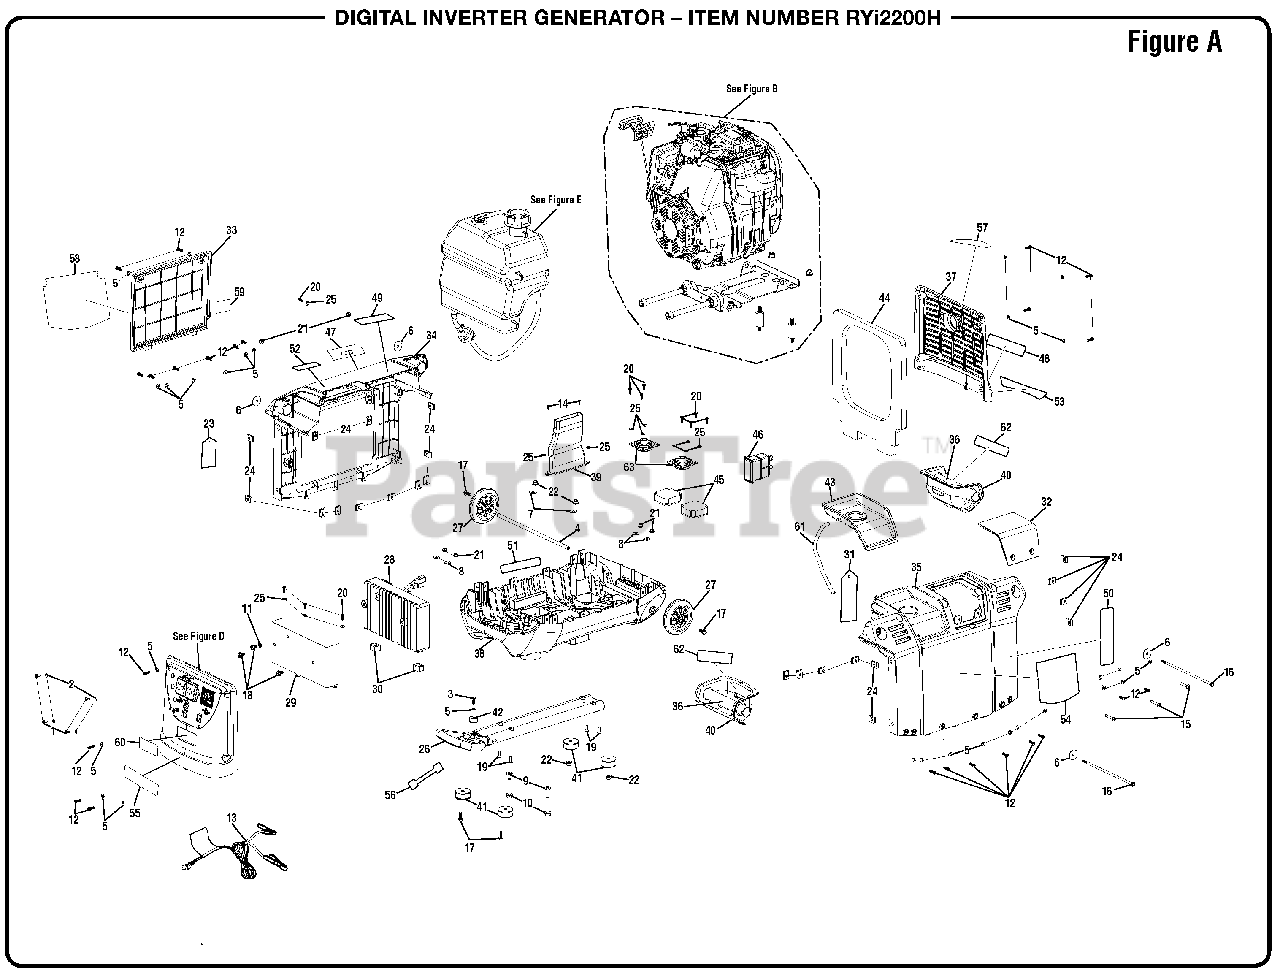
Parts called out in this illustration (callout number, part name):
1	Screw w/Washer (M4 x 10 mm, T20 Torx Hd)
2	Flat Washer (OD8 x ID43 x 05t)
3	Screw (M5 x 14 mm, Phillips Hd)
5	Washer (OD10 x ID53 x 1t)
6	Washer (OD25 x ID63 x 15t)
7	Washer (OD18 x ID63 x 15t)
8	Washer (OD15 x ID53 x 1t)
9	Washer (OD16 x ID83 x 2t)
10	Bolt (M8 x 40 mm, Hex Hd)
11	Star Washer (OD11 x ID64 x 06t)
12	Screw (M5 x 14 mm)
13	DC Cable Assembly
14	Screw (ST35 x 9 mm)
15	Screw (M5 x 30 mm, Side Housing)
16	Bolt (M5 x 195 mm)
17	Bolt (M6 x 16 mm, Flange Hex Hd)
18	Bolt (M6 x 12 mm, Hex Hd)
19	Screw (M5 x 14 mm)
20	Screw (M42 x 12 mm)
21	Flange Nut (M5)
22	Lock Nut (M6)
23	Initial Starting Hangtag
24	U-Clip (M5)
25	Washer (OD10 x ID42 x 1t)
26	Handle Assembly
28	Inverter Module
29	Air Guide Sheet
30	Inverter Bottom Support
31	Warning Hangtag
32	Spark Plug Cover
33	Maintenance Assembly (Includes Labels & Sound Foam)
34	Left Side Housing Assembly (Includes Labels & Sound Foam)
35	Right Side Housing Assembly (Includes Labels & Sound Foam)
36	Handle (Upper)
37	Muffler Cover
38	Base
39	Air Filter Duct
40	Handle Cover Assembly (Includes Labels & Sound Foam)
41	Foot Assembly
42	Rubber Bumper
43	Fuel Overspill Guard
44	Foam Pad (Muffler)
45	Foam Pad (Base)
46	Carbon Canister
47	Quick Start Label
48	Combustion Label
49	CPSC Label
50	Danger Label
51	Data Label
52	E85 Label
53	Fire Distance Label
54	Performance Label
55	Ground Warning Label
56	Handle Release Label
57	Hot Surface Label
58	Logo Label
59	Check Oil Label
60	Logo Label (small)
61	Vapor Hose (Carbon Canister To Air Box)
62	Warning Transport w/Handle Label
63	Isolator (Engine Bracket)
